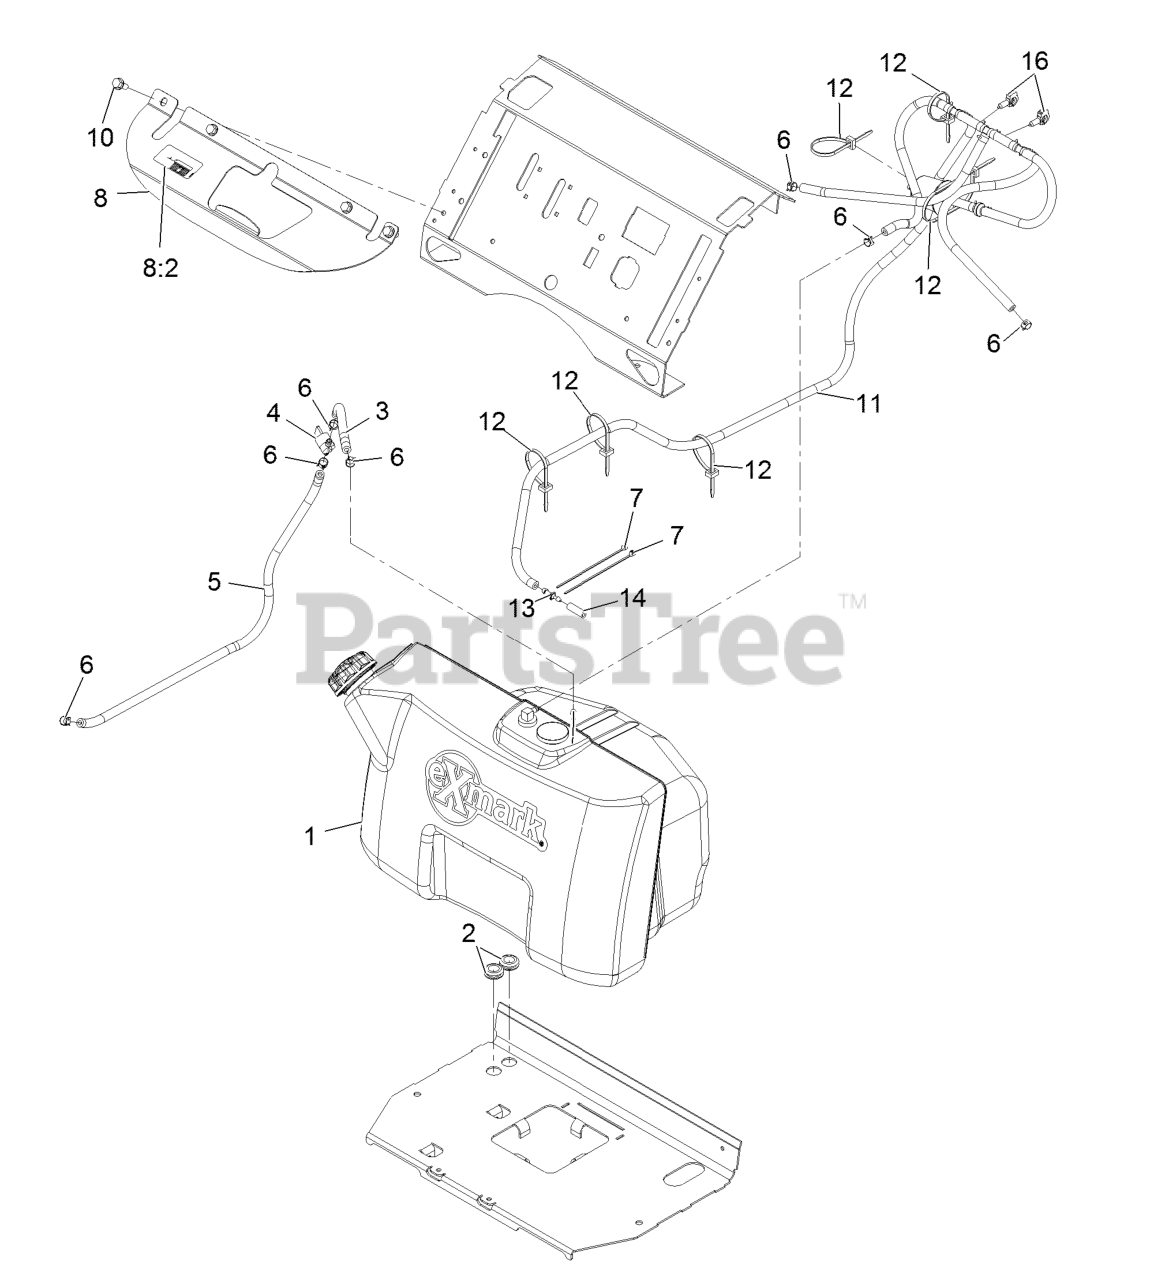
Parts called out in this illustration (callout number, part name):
2	GROMMET
3	HOSE-FUEL
4	VALVE-FUEL
5	HOSE-FUEL
6	CLAMP-HOSE
7	TIE-CABLE
8	BRACKET-TANK
8:2	DECAL-FILL, FUEL
10	Screw-HWH 5/16-18 X 3/4 Tf
11	VENT ASM
12	TIE-CABLE
13	FITTING-STRAIGHT
14	HOSE-FUEL
16	CLIP-HARNESS
